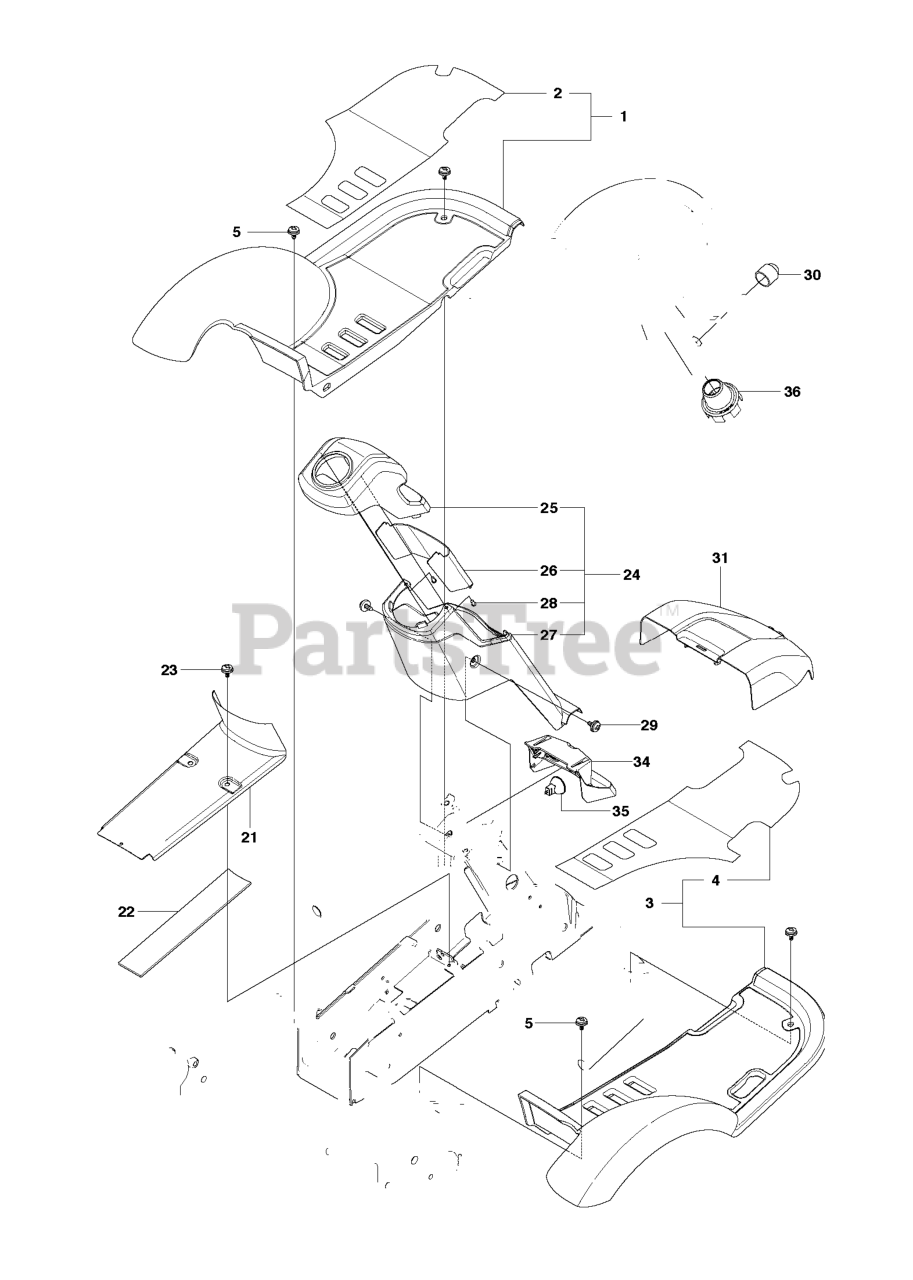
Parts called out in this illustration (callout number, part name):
1	FOOT PLATE
3	FOOT PLATE
30	PROTECTIVE COVER
31	UNIT COVER
